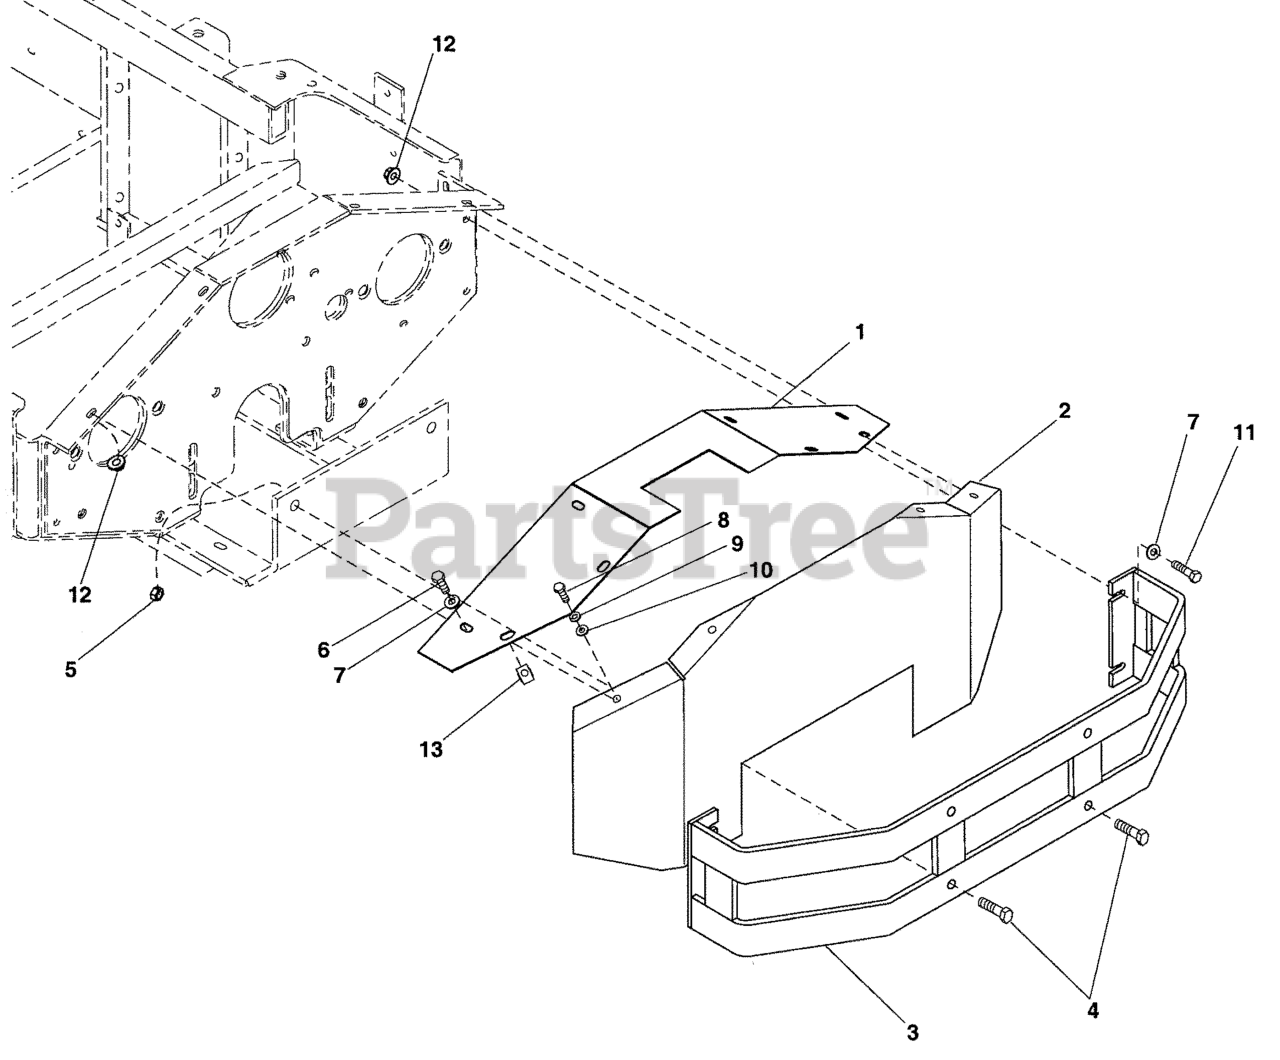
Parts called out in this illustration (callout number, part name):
1	SUPPORT COVER, REAR
2	SHIELD, REAR
4	BOLT, 1/2-20 X 1-1/2, GD5 CZ
5	NUT, Hex, Nylon Lock, 1/2-20
6	BOLT, 3/8-16 X 1" GD5 CZ
7	WASHER, 3/8 SAE
8	BOLT, 5/16-18 X 1 GD5 YZ
9	WASHER, 5/16 LOCK CZ
10	WASHER, 5/16" SAE
11	BOLT, 3/8-16 X 1-1/2" GD5 CZ
12	NUT, Serrated Flange, 3/8-16
13	BODY CLIP, 5/16-18-7GA MATERIAL
